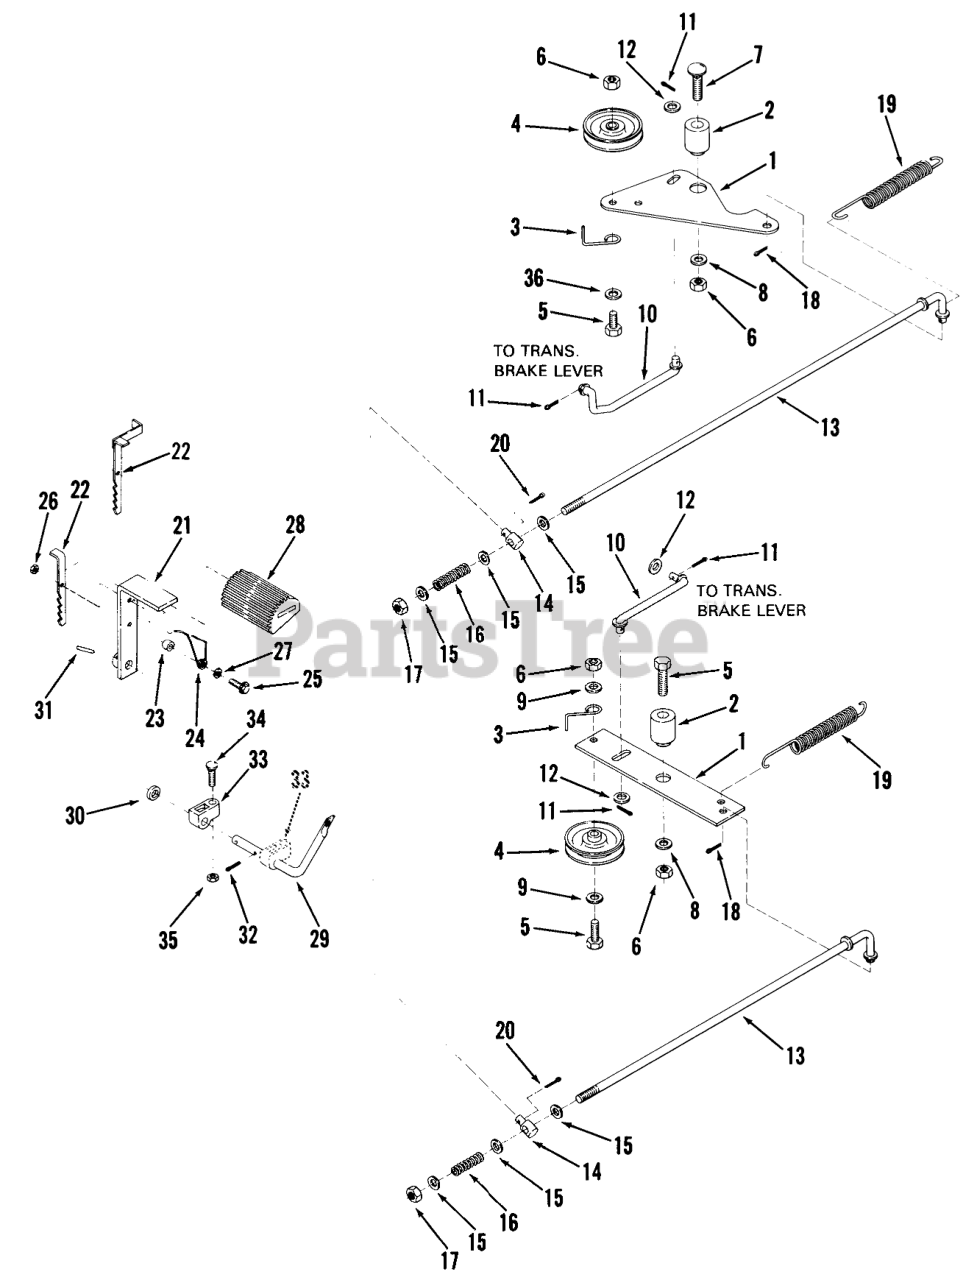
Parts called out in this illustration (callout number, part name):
1	Idler Arm
2	SPACER-CLUTCH ARM
2	Spacer
3	Snap Ring
4	PULLEY-IDLER STATION
5	Bolt
6	Nut
7	Bolt
8	WASHER
9	Washer
10	Brake Rod
11	Cotter Pin
12	WASHER-NYLON
12	Washer-3/8
13	Clutch Rod
14	TRUNNION-LIFT
15	Washer
16	Spring-Clutch/Brake Overtravel
17	Nut
18	Cotter Pin
19	SPRING
20	Cotter Pin
21	Clutch/Brake Pedal
22	Park Brake Lever-Early Production Models Only
22	Park Brake Lever
23	SPACER
24	Spring-Park Brake Lever
25	Bolt 10-24 X 1 Washer HD
26	Nut
27	WASHER
28	Pad, Brake Pedal
29	Clutch/Brake Arm
30	Spacer
31	Roll Pin
33	BLOCK-MTG NEW RETURN
34	Bolt
35	Nut
36	Washer
